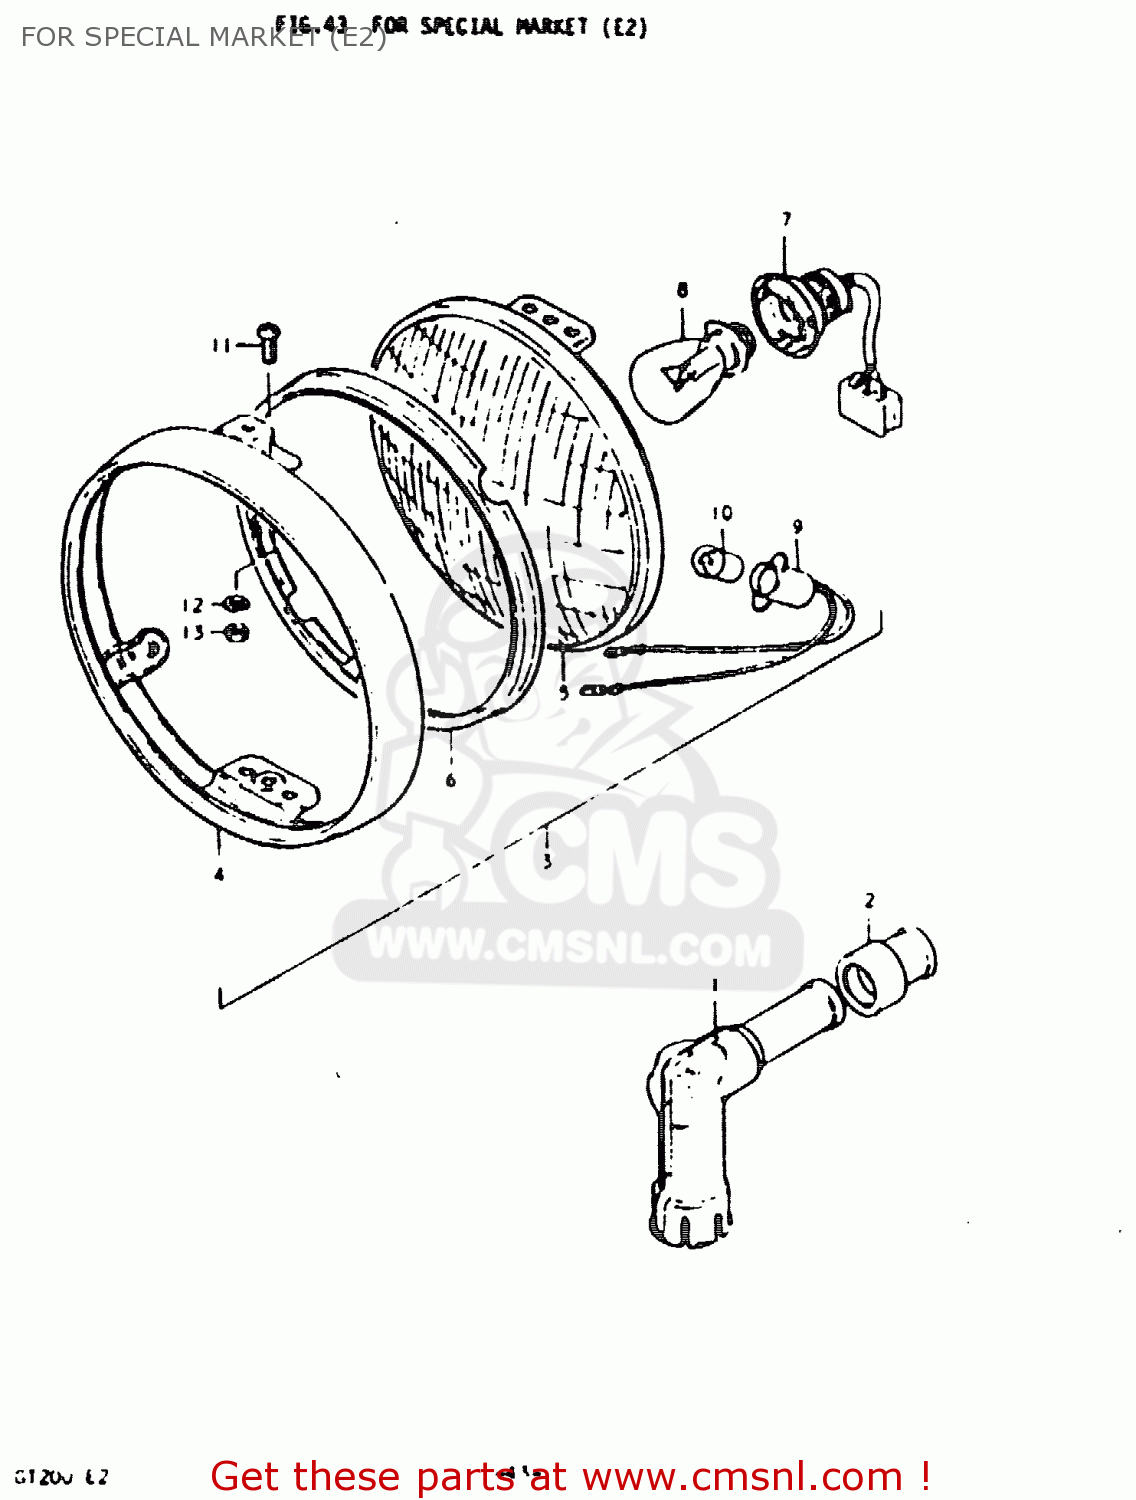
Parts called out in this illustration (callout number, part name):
1	CAP,SPARK PLUG
2	SEAL,SPARK PLU
3	HEADLAMP ASSY
4	RIM
5	UNIT, HEAD LIGHT
6	RETAINER,HEADLAMP
7	SOCKET
8	BULB 12V35/35W
9	SOCKET
10	BULB(12V3.4W,STANLEY,A72A)
11	SCREW
12	LOCK WASHER
13	NUT
